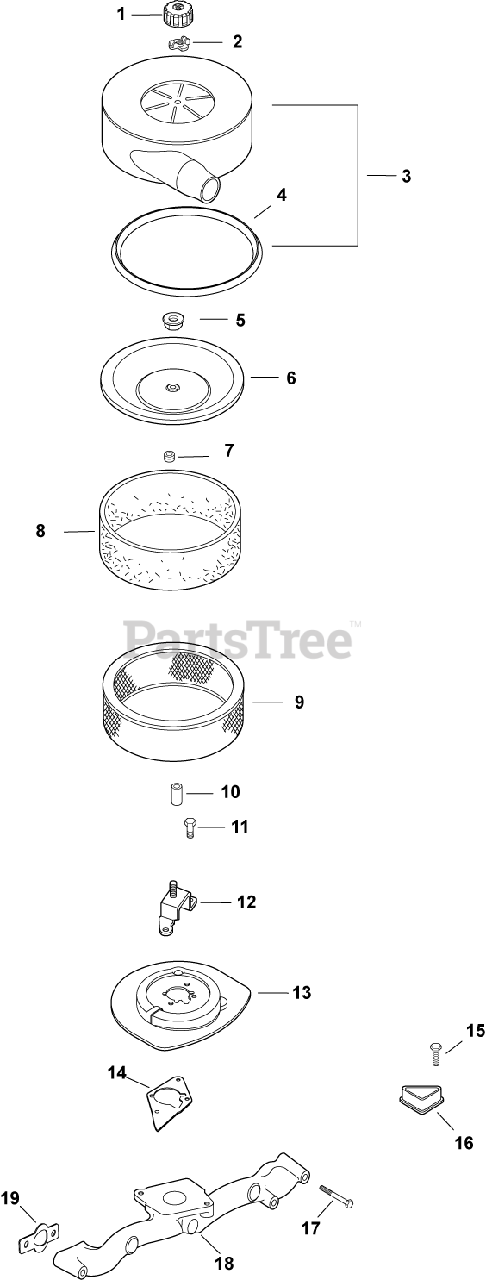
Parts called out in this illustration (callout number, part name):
2	NUT, WING
3	COVER, AIR CLEANER
4	KIT, AIR CLEANER COVER SEAL
5	NUT, FLG M6X1.0
6	COVER, INNER AIR CLEANER
7	SEAL, INNER AIR CLEANER
8	PRE-CLEANER (HIGH)
9	ELEMENT, AIR FILTER (HIGH) - Also available Retail Packaged 24 883 03-S1 Air Filter Kit
10	SEAL, BREATHER
11	SCREW, FLG THD FRM M6X1.0X16
12	BRACKET ASSY,AIR CLEANER-USE 24 126 211-
13	BASE, AIR CLEANER-USE 24 094 91-S
14	GASKET, AIR CLEANER BASE
15	SCREW, WSH HD TAP #8-18X1/2"
16	COVER, BLOWER HOUSING USE 24 096 160-S
17	SCREW, FLG M6X1.0X55
18	MANIFOLD, METAL INTAKE
19	GASKET, INTAKE MANIFOLD USE 24 041 79-S
